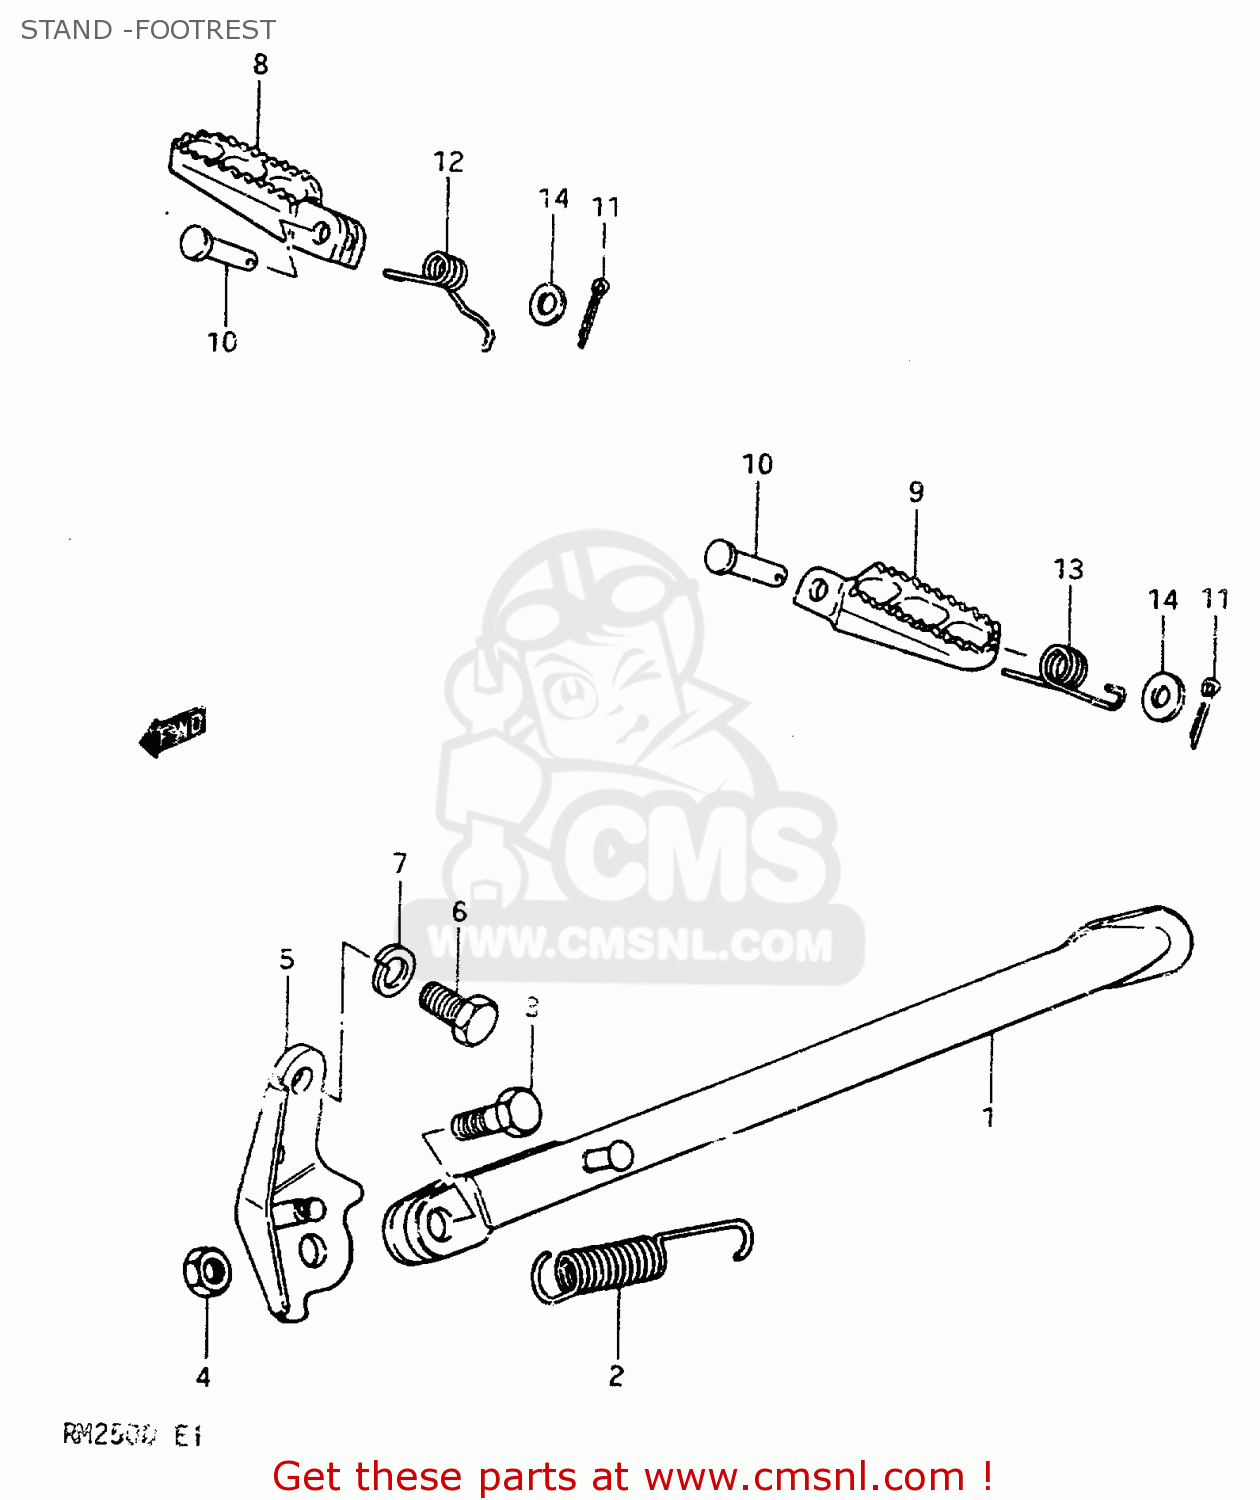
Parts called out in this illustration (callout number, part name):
1	STAND,SIDE
2	SPRING
3	BOLT(10X30)
4	NUT
5	BRACKET,SIDE STAND
6	BOLT(10X19)
7	WASHER,LOCK,10
8	FOOTREST,FR,R
9	FOOTREST,FR,L
10	PIN
11	PIN 20X20
12	SPRING
13	SPRING,FOOTREST,LEFT
14	WASHER
